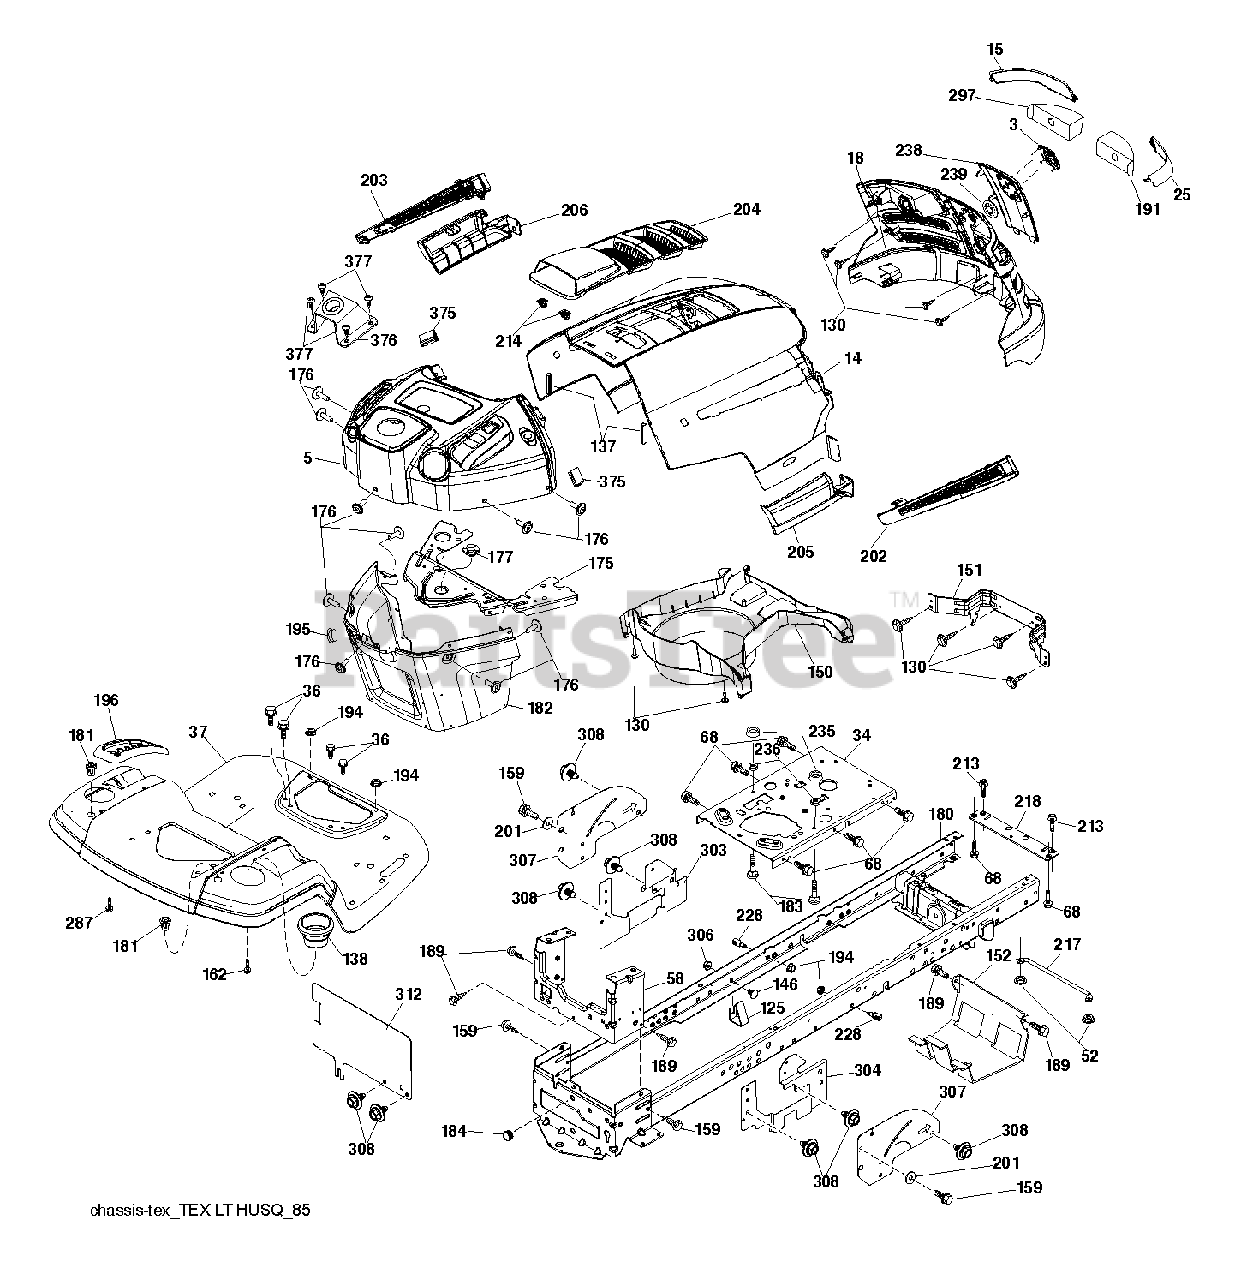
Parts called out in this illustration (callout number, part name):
3	LOGO.HUSQ.GT.LT.CROWN.H
5	DASH.UPPER.HUSQ.LT.MAN.NO-CHK
14	HOOD.HUSQVARNA.LT.ORANGE
15	LENS.HUSQVARNA LT.RH
18	GRILLE.SVC.HUSQVARNA.GREY
25	LENS.HUSQVARNA LT.RH
34	PLATE.ENGINE.WELDED.CHASSIS
36	SCREW 5/16"
37	FENDER.TLT.FS.W/CUPHLD.ORANGE
52	LOCKNUT
58	DRAWBAR UPPER 2PC SMALL FENDER
68	SCREW LT
125	CLIP.FUEL.LINE
130	SCREW.#10 X 0.750.BOS
137	BUMPER DASH
138	HOLDER.CUP.LT.GREY
146	BOLT.RDHD.SHT.SQNK.3/8-16X5/8
151	BRACKET PIVOT
152	SHIELD.BROWNING.W/TEX
159	SCREW, 3/8-16X3/4
162	SCREW.HI-LO.CONSOLE
175	CROSSMEMBER
176	SCREW.#10-24X5/8.RN.QU
177	BUSHING STEERING
180	CHASS.WLDMNT.TL.12GA/2P.48/54
181	BUSHING.MNT.FEND.CRGO.TEX.49
182	DASH.LOWER.PREDATOR LT
183	BOLT.5/16-18X1-1/4 FULL THD
184	PLUG.DEMO.625
189	SCREW
191	INSERT.REFLECTIVE.RH.
194	NUT LOCK HEX FLANGE 5/16-18
195	PLUG.TEX.DASH.SVC.MINDER.GREY
196	DECKLFT.CONSOL FULL ASSM GREY
201	WASHER
202	VENT.SIDE.HUSQVARNA.LT.RT
203	VENT.SIDE.HUSQVARNA.LT.LFT
204	SUBASM.TOP.VENT.HUSQ.LT
205	SKIRT.SIDE.HUSQVARNA.LT.RT
206	SKIRT.SIDE.HUSQVARNA.LT.LEFT
213	BOLT
214	CLIP.RETAINER.TINNER.
217	ROD.PIVOT.HOOD
218	X-PIECE.HOOD.STOP.NON/
228	STUD.FASTNER.W/ANTI-ROTATE
235	SPACER FENDER
236	NUT.CENTERLOCK.5/16-
238	TRIM.HUSQ LT.668
287	SCREW 1/4X20
297	INSERT REFLECTIVE
303	SHIELD.LOWER.LH/LT/GT/BLK.EDIP
304	SHIELD.RH.LOW.LTGT.NO
306	NUT LOCK FLG 3/8-16 UNC
307	SHIELD.UPPER.LT.GT.ISO
308	BOLT, 5/16-18 X 1 3/4
312	SHIELD.DRAWBAR.LT.FRNTTANK.431
375	BUMPER CLIP-ON. DASH 1"
376	MOUNT.ASM.HUSLT.UPPER.STRNG
377	SCREW 10 X 1/2 ZN PL PHIL PAN
